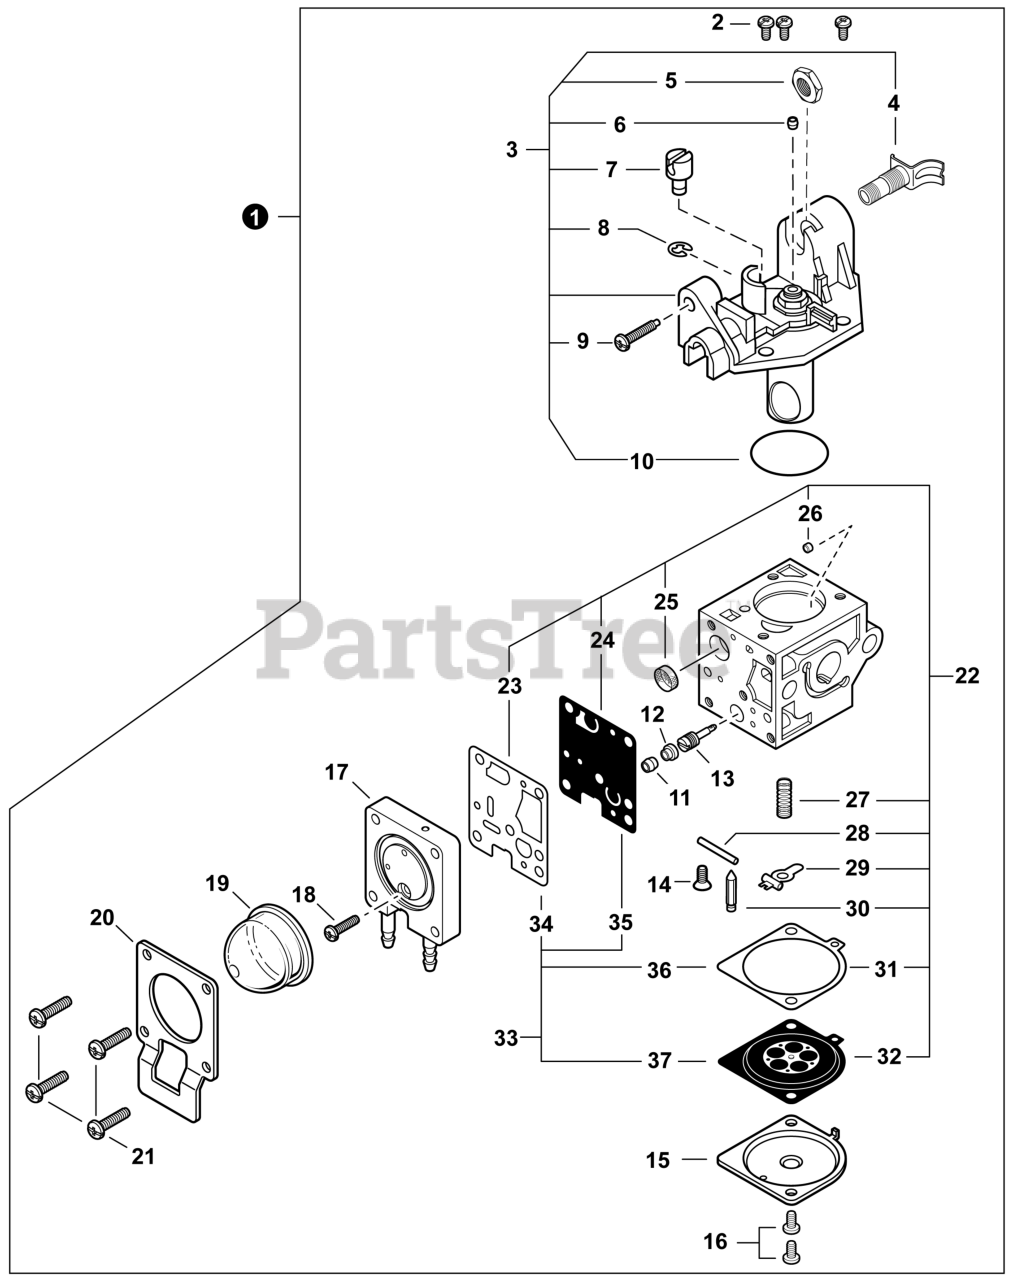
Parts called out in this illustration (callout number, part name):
1	CARBURETOR - Z011-0OA
2	SCREW
3	COVER KIT, ROTOR
4	ADJUSTER, CABLE
5	NUT
6	PLUG
7	SWIVEL
8	E-RING
9	SCREW, THROTTLE ADJUST
10	O-RING
11	PLUG
12	CAP, LIMITER
13	NEEDLE, HIGH SPEED
14	SCREW
15	COVER, METERING DIAPHRAGM
16	SCREW
17	BODY ASSY, PURGE
18	SCREW
19	BULB, PURGE
20	RETAINER, PURGE BULB
21	SCREW
22	REPAIR KIT, CARBURETOR
23	GASKET, PUMP
24	DIAPHRAGM, PUMP
25	SCREEN, FUEL INLET
26	GUIDE, ROLLER
27	SPRING, METERING LEVER
28	PIN, METERING LEVER
29	LEVER, METERING
30	VALVE, INLET NEEDLE
31	GASKET, METERING DIAPHRAGM
32	DIAPHRAGM, METERING
33	GASKET / DIAPHRAGM KIT
34	GASKET, PUMP
35	DIAPHRAGM, PUMP
36	GASKET, METERING DIAPHRAGM
37	DIAPHRAGM, METERING
